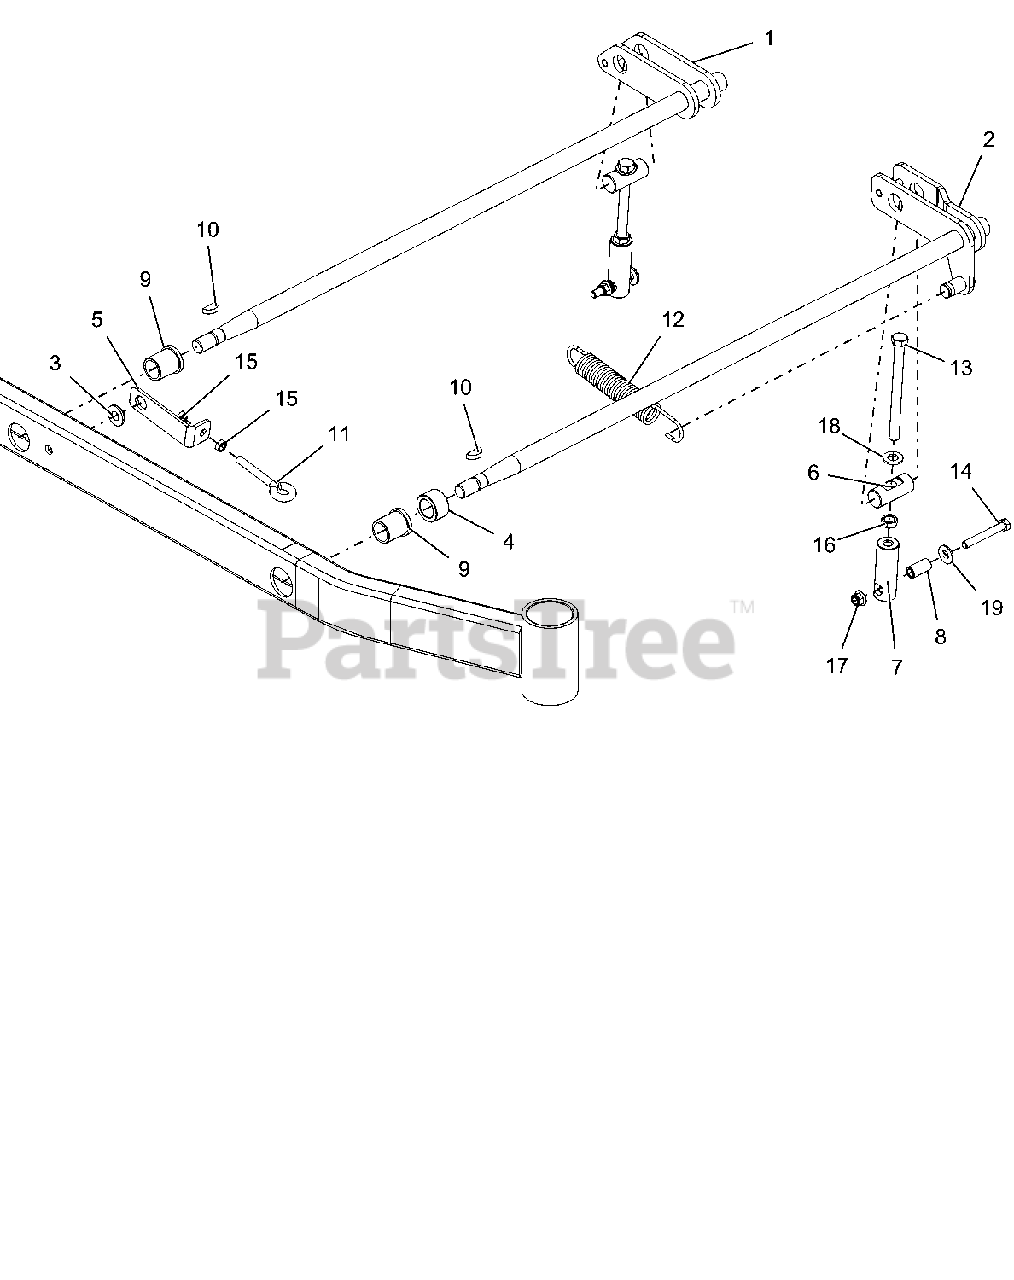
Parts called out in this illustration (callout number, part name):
1	WLDMT, REAR LH DECK LIFT ARM (BLACK)
2	WLDMT, FRONT LH DECK LIFT ARM (BLACK)
3	BSHG, FLANGE .515X.750X.31X1.12
4	SPACER, 1.500 X 1.000 X .880
5	BRKT, SPRING ANCHOR (RED)
6	PIN, DECK LIFT
7	LINK, DECK LEVELING
8	SPCR, DECK LEVELING
9	BSHG-FLG 1.00X1.25X1.5X1.5
10	KEY, WDRF .25 X 1.00 HRD #15
11	BOLT, EYE .375-16
12	SPRG, TENSION .162 X 1.250 X 8.250
13	BLT-HEX .50-13X6.00 2.5 THD GR5 YWZC
14	BLT-HEX .38-16X2.75 GR8 YWZC
15	NUT, JAM .375-16 YWZC
16	NUT, JAM .500-13 YWZC
17	NUT-LK-NYL-FLG .38-16 YWZC
18	WSHR-FL-STL .557X1.040X.102 YWZC HARD
19	WSHR-FL-STL.438X1.00X.083 YWZC
